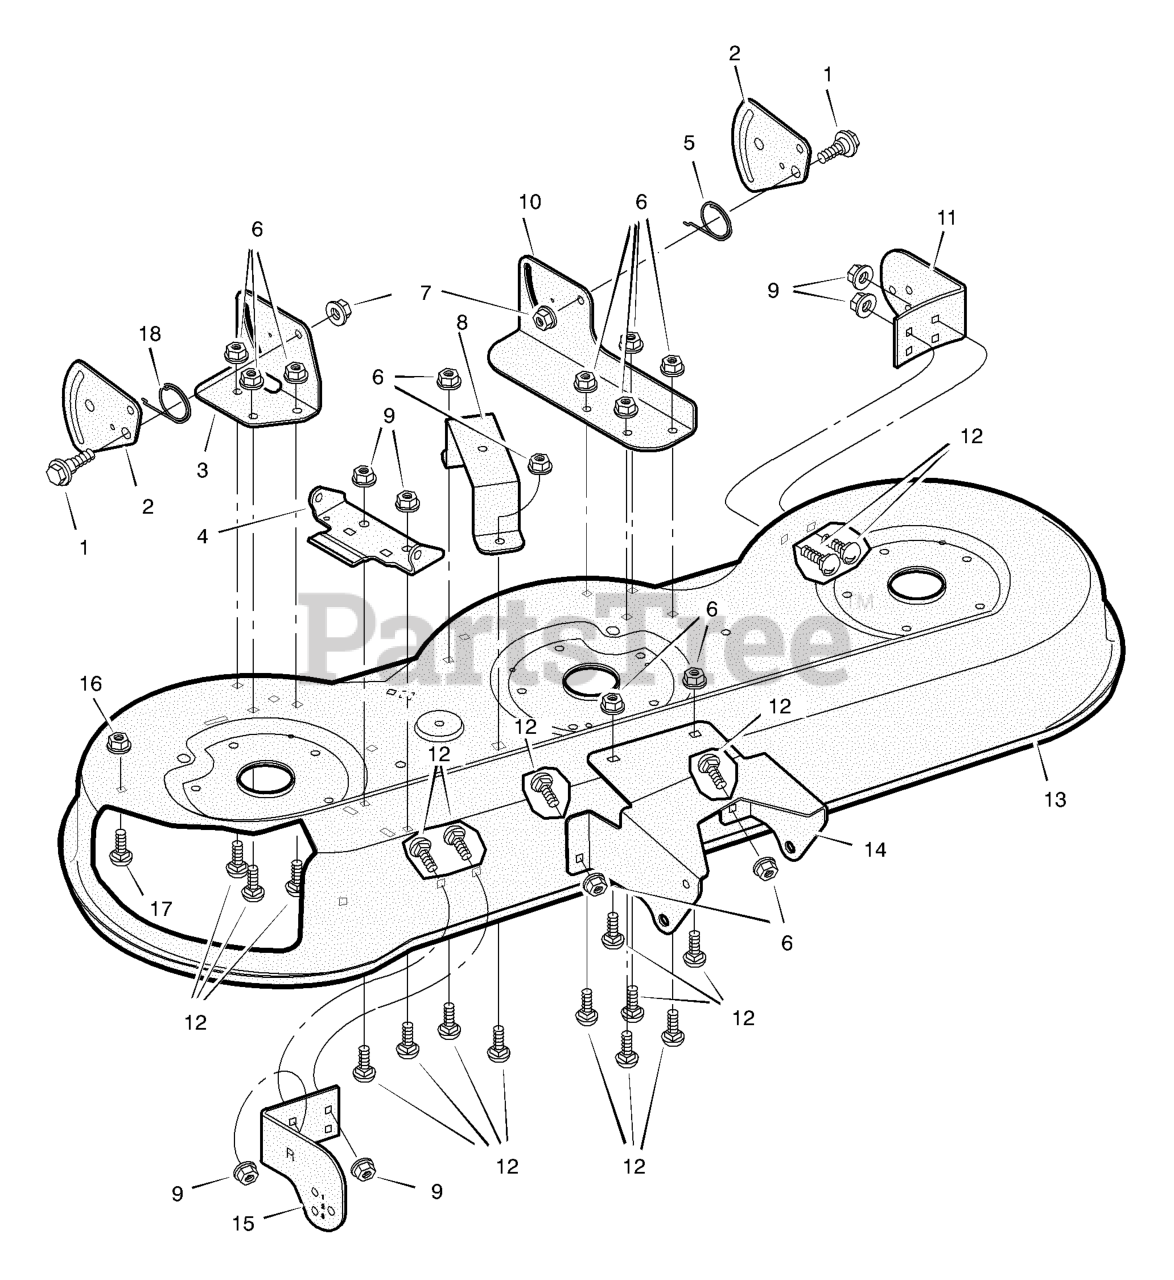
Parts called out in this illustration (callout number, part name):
1	Bolt, Shoulder
2	Plate, Suspension
3	Bracket, Right Rear
4	Bracket, Hinge
5	Spring, Left
6	Nut, Flange
7	Nut, Flange
8	Bracket, Bell Crank
9	Nut, Flange
10	Bracket, Left Lifter
11	Bracket, Left Gauge Wheel
12	Bolt, Carriage
13	Housing, Blade
14	Bracket, Front Deck
15	Bracket, Right Gauge Wheel
16	Retainer
17	Bolt, Carriage
18	Spring, Right
